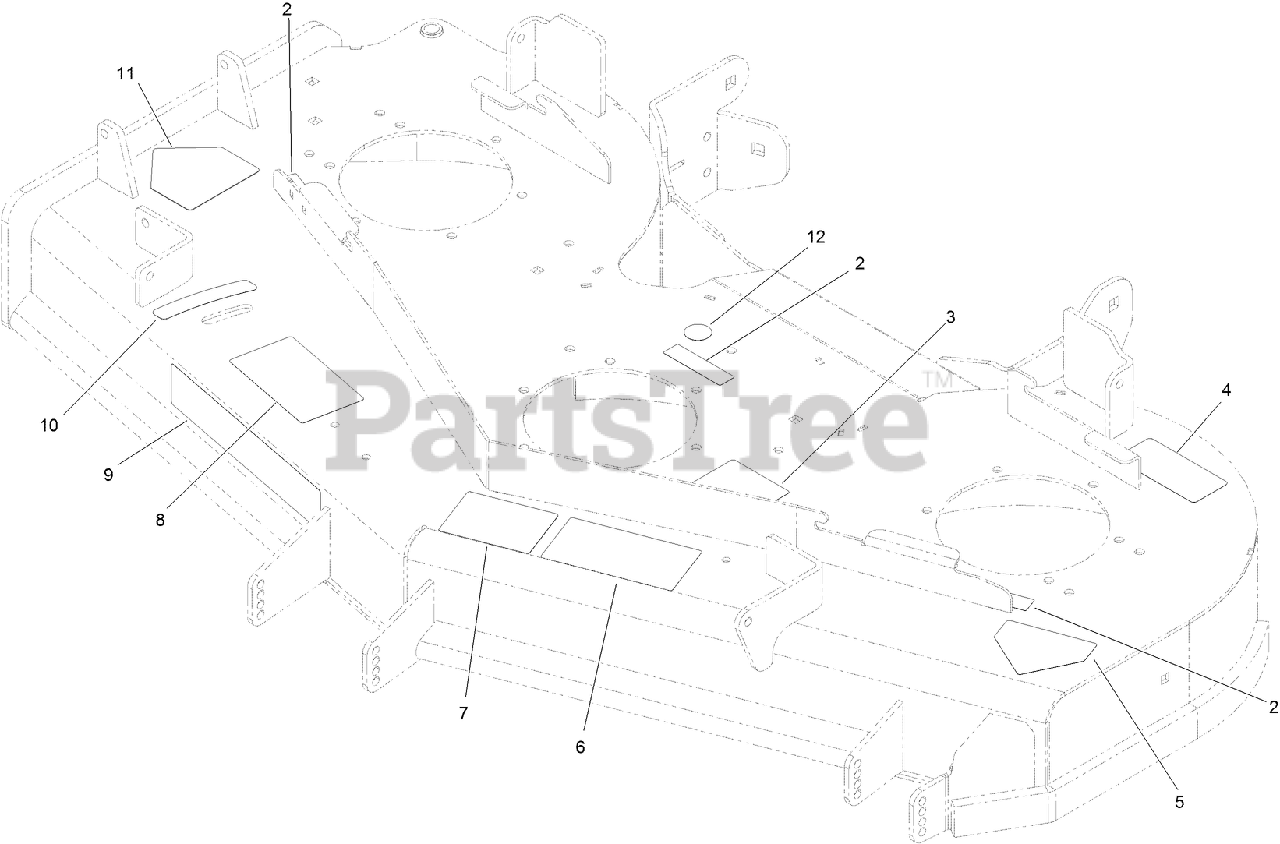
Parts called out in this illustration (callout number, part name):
2	DECAL-COVER, MISSING
3	DECAL-ROUTING, DECK BELT
4	DECAL-TORQUE
5	DECAL-DANGER
6	DECAL-DANGER, THROWN OBJECT
7	DECAL-SCALP, ANTI
8	DECAL-ADJUSTMENT, BAFFLE
10	DECAL-SETTING, BAFFLE
11	DECAL-DANGER
12	DECAL-GREASE
